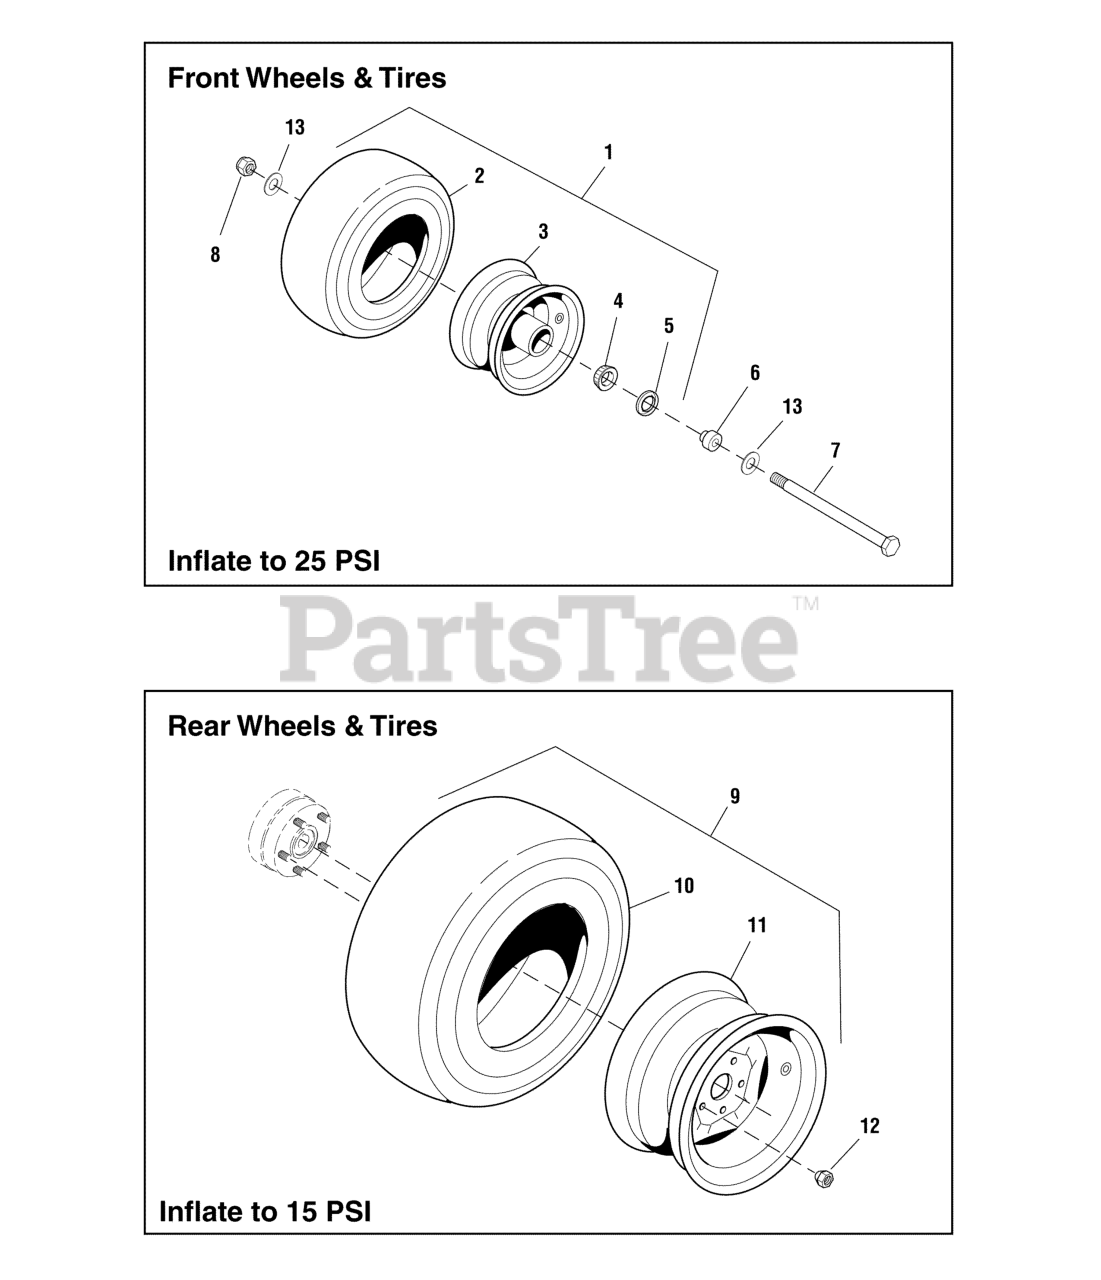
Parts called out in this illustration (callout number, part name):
1	WHEEL & TIRE ASSEMBLY, 13 x 5.0 - 6, Complete
1	* FLAT-FREE TIRE ASSEMBLY, 13 x 5.0 - 6
2	TIRE, 13 x 5.0 - 6
3	WHEEL ASSEMBLY, for 13 x 5.0 - 6 Tire, Complete
4	BEARING, TAPERED CONE
6	ADAPTER, Caster Wheel
7	BOLT, 1/2-13 x 8"
8	NUT, 1/2-13 Hex Nylon Lock
9	WHEEL & TIRE ASSEMBLY, 22 x 11 - 10, Complete
10	TIRE, 22 X 11.0 - 10
11	WHEEL ASSEMBLY, 10 X 7
12	LUG NUT, 1/2-20
13	WASHER, 1/2" SAE
